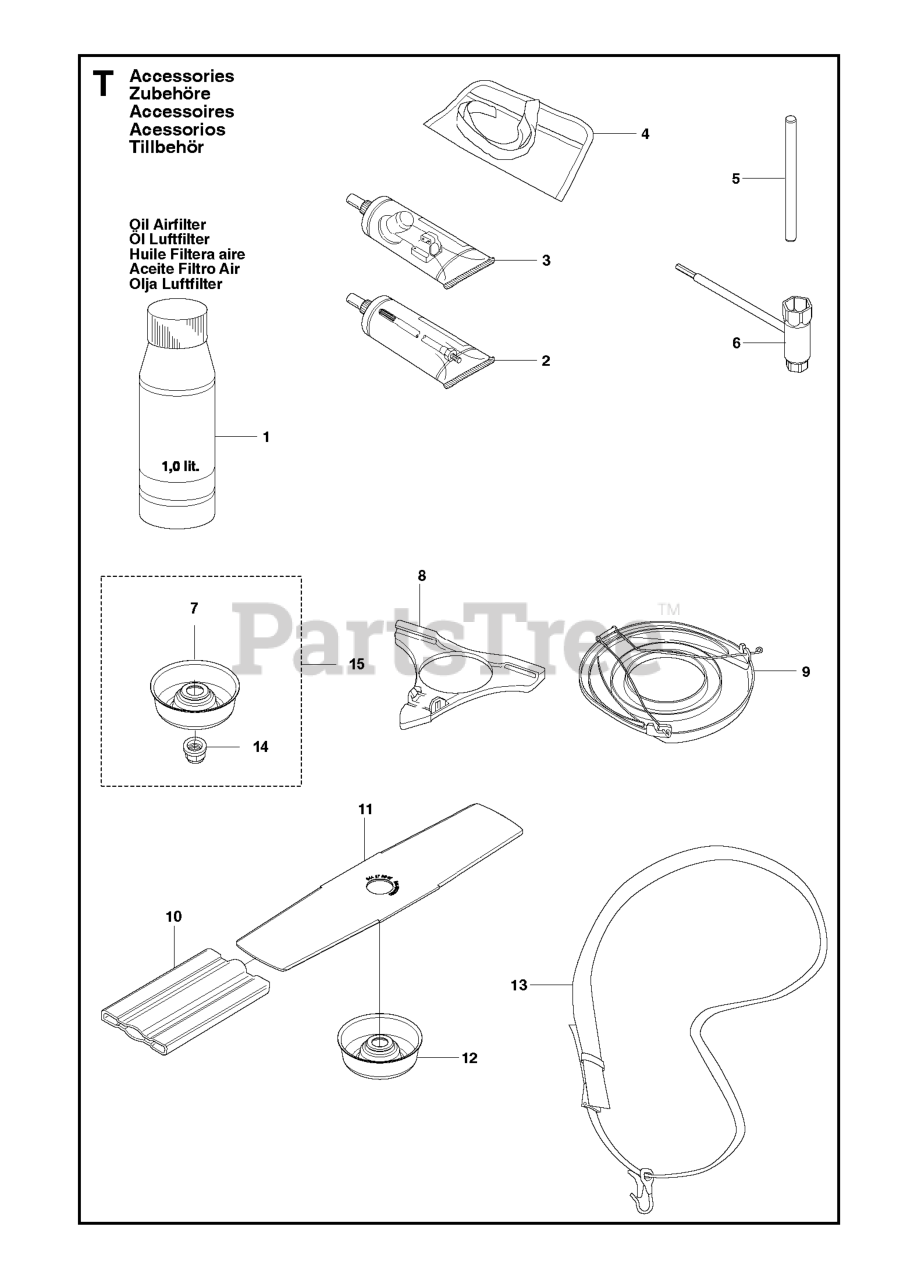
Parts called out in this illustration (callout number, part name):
1	Air Filter Oil 1l.
2	DRIVE SHAFT GREASE (200 G)
3	BEVEL GEAR GREASE
5	LOCKING PIN
6	RP COMBI TOOL
7	SUPPORT CUP
8	TRANSPORT GUARD
9	BLADE GUARD TRANSPORT
12	SUPPORT CUP
13	Harness-w/o warning
